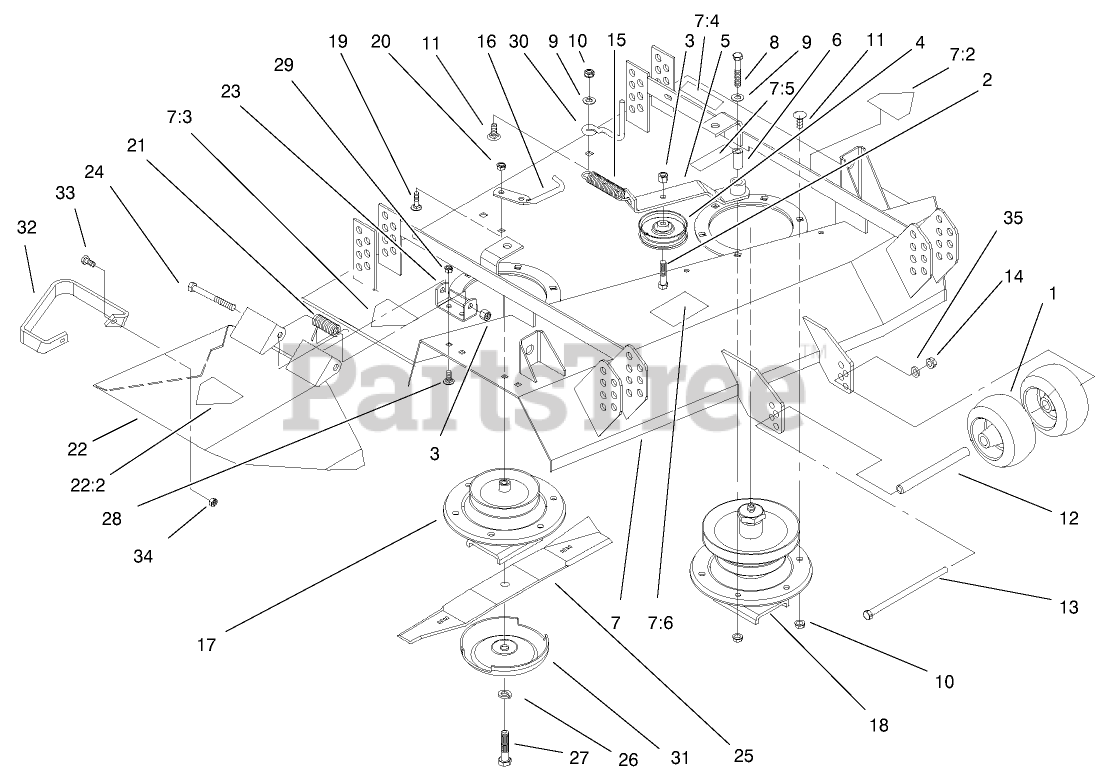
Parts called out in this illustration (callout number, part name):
1	WHEEL-GAGE
2	SCREW-HH
3	NUT-HEX
4	PULLEY-IDLER
5	IDLER ARM ASM
6	SLEEVE-PIVOT, IDLER
7	DECK ASM
7:2	DECAL-DANGER
7:3	DECAL-DANGER
7:4	DECAL-TORQUE
7:5	DECAL-DANGER
7:6	DECAL-DANGER, THROWN OBJECT
8	SCREW-HH
9	WASHER-FLAT
10	NUT-HF
11	SCREW-CARR
12	SPACER-WHEEL
13	SCREW-HH
14	NUT-LOCK, NI
15	SPRING-EXTENSION
16	ROD - SPRING
17	BEARING
18	HOUSING - SPINDLE ASM
19	SCREW-CARR
20	NUT-LOCK, NI
21	SPRING
22	DEFLECTOR ASM
22:2	DECAL-DANGER
23	BRACKET-PIVOT
24	SCREW-HH
25	BLADE-SAIL, EXTRA HIGH
26	WASHER-LOCK
27	SCREW-BLADE
28	SCREW-CARR
29	NUT-LOCK, CONE
30	ROD-BELT
31	CUP-SCALP, ANTI
32	GUARD - DEFLECTOR
33	SCREW-HH
34	NUT-LOCK, NI
35	WASHER-PLAIN
